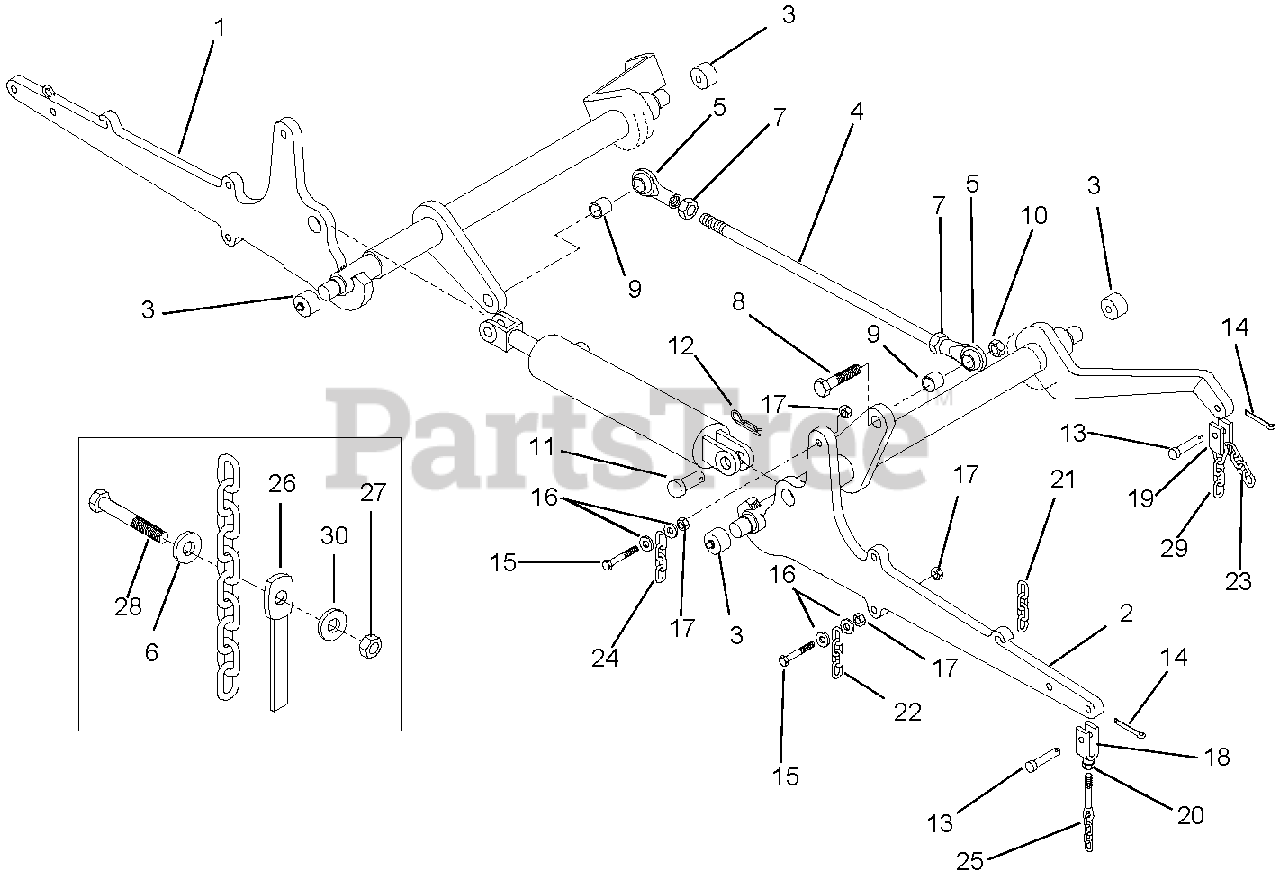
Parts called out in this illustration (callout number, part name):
1	Weldment, Hydraulic Lift Arm Left Hand
2	Weldment, Hydraulic Lift Arm Right Hand
3	Assembly, Bearing Cup
4	Rod, Synchronizing
5	Rod End .75
6	Washer, Fender .25
7	Nut, Jam .75
8	Cap Screw .75-10 x 3
9	Spacer, Equalizer Rod
10	Nut, Hex .75-10
11	Pin, Clevis 1 x 2.25
12	Pin, Cotter Hair .125
13	Pin, Clevis .375 x 1
14	Cotter Pin 5/32 x 1
15	Cap Screw, Hex Head .375-16 x 1.75
16	Washer, Flat .375
17	Nut, Jam .375-16
18	Clevis Yoke, Modified
19	Clevis Yoke
20	Nut, Hex .375-16
21	Chain, Transport
22	Lift Chain, #1
23	Lift Chain, #2 and #3 Outer
24	Lift Chain, #4 and #5 Inner
25	Lift Chain, #4 and #5 Outer
26	Strap, Tarp 8.25" No Hook
27	Nut, Hex .25-20 Nylock
28	Cap Screw, Hex Head .25-20 x 1-1/2
29	Lift Chain, #2 and #3 Inner
30	Washer, Flat 1/4 USS
